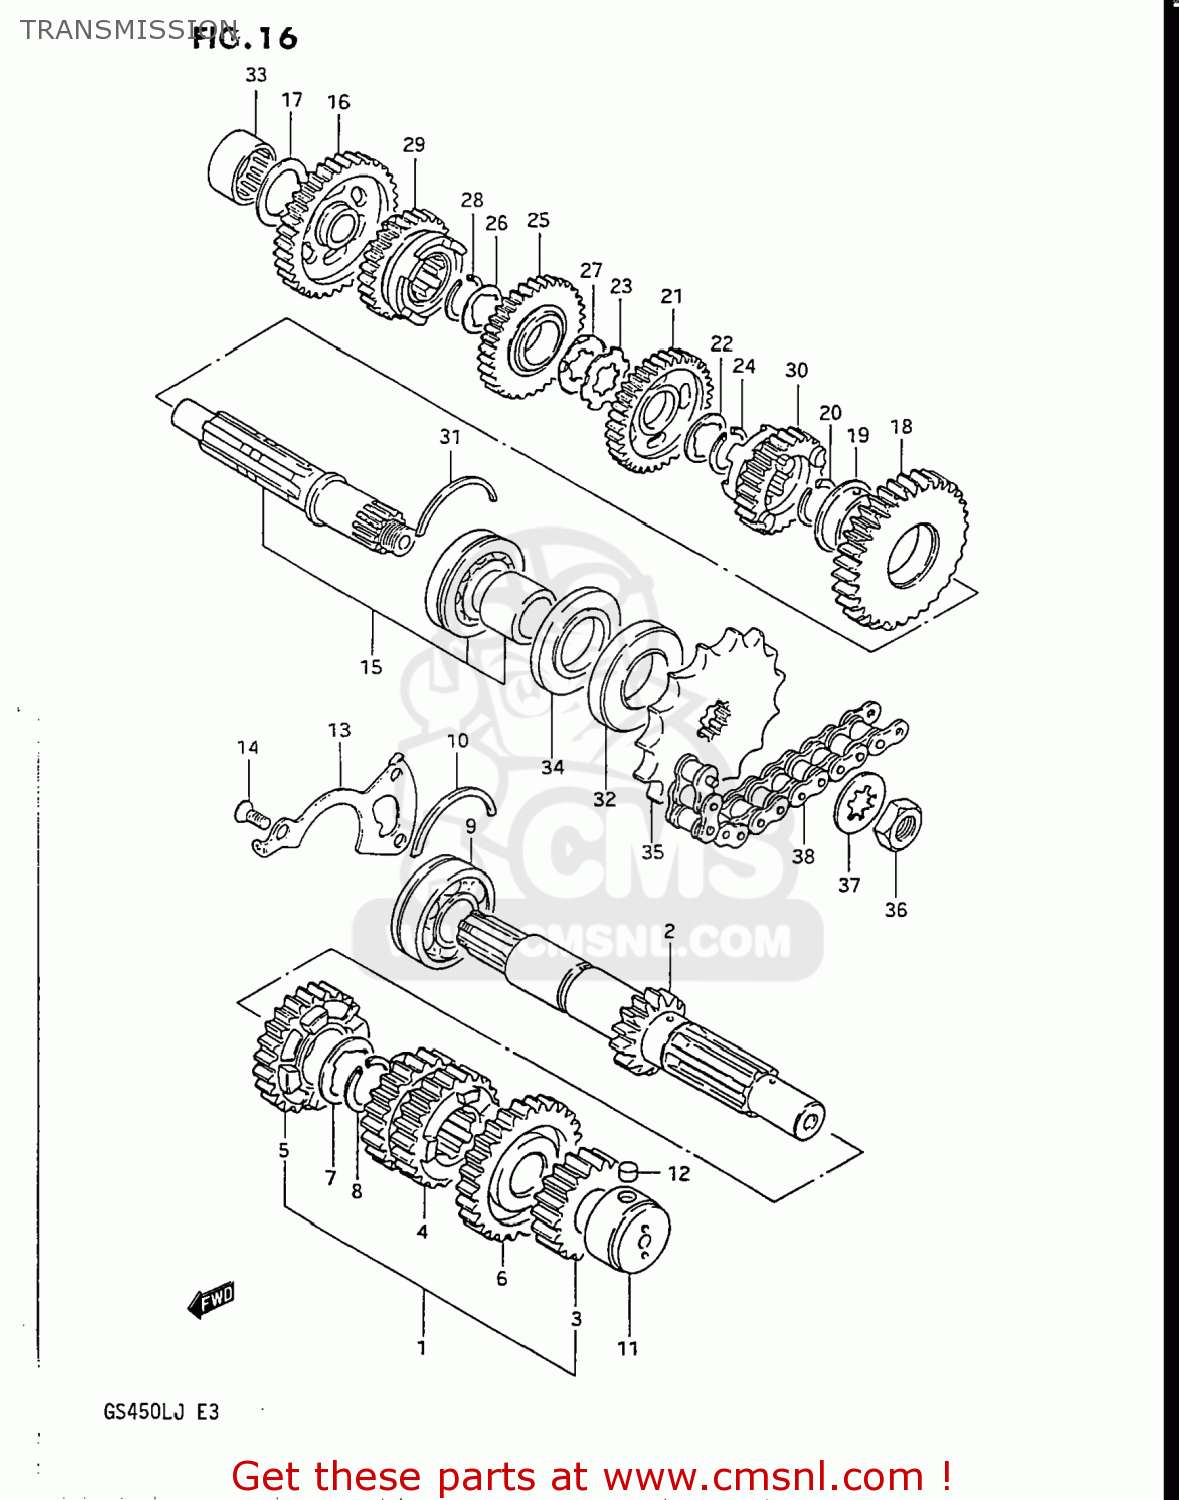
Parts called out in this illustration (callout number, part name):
1	SHAFT,COUNTER
2	SHAFT,COUNTER
3	GEAR,2ND DRIVE(NT:18)
4	GEAR,THIRD DRIVE
5	GEAR,FIFTH DRIVE
6	GEAR,SIXTH DRIVE
7	WASHER
8	CIRCLIP
9	BEARING(25X62X17)
10	C-RING
11	ROLLER BEARING (20X34X2
12	PIN
13	PLATE,COUNTERSHAFT BEARING
14	SCREW
15	SHAFT,DRIVE
16	GEAR,FIRST DRIVEN
17	WASHER
18	GEAR,SECOND DRIVEN
19	BUSHING
20	CIRCLIP
21	GEAR,THIRD DRIVEN
22	WASHER,LOCK
23	WASHER,LOCK
24	CIRCLIP
25	GEAR,FOURTH DRIVEN
26	WASHER,LOCK
27	WASHER
28	CIRCLIP
29	GEAR,5TH DRIVEN(NT:25)
30	GEAR,SIXTH DRIVEN
31	C-RING
32	SEAL,OIL(32X62X7)
33	ROLLER BEARING (20X34X1
34	SEAL,OIL(32X62X5.5)
35	SPROCKET,ENGINE(NT:16)
36	NUT
37	WASHER
38	CHAIN,DRIVE #50UB-108
